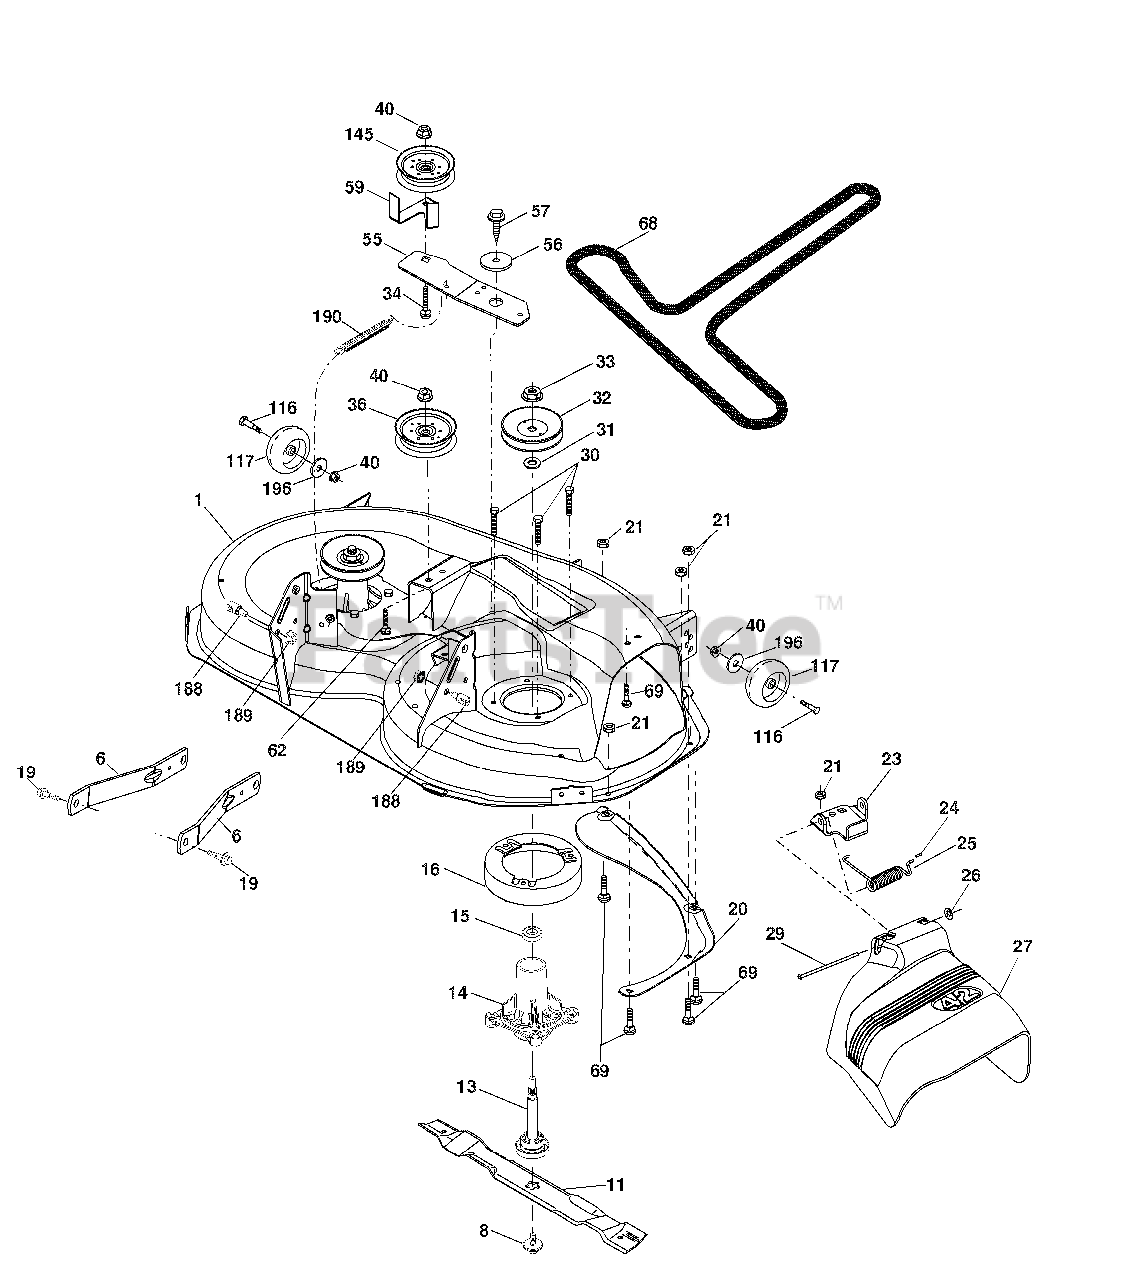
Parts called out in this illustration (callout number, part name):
1	Mower Housing
6	Arm Suspension
8	Bolt/Washer asm 7/16-20 unf
11	Blade, 42" Hi-Lift
13	Shaft Assembly, Mandrel
14	Housing, Mandrel
15	Bearing, Ball, Mandrel
16	Stripper, Mower Deck
19	Bolt, Shoulder
20	Baffle, Vortex
21	Nut, Crownlock 5/16-18 unc
23	Bracket, Deflector
24	Cap, Sleeve
25	Spring, Torsion, Deflector
27	Shield, Deflector
29	Rod, Hinge
30	Screw Thdrol Rolling Wsh Hd
31	Washer, Spacer
32	Pulley, Mandrel
33	Nut, Toplock, Flanged
34	Bolt Carr Sh. 3/8-16 x 1-1/2 Gr. 5
36	Pulley, Idler, Flat
40	Nut, Lock Flg. 3/8-16 unc
55	Arm, Idler
56	Spacer, Retainer
57	Screw 3/8-16 x 1
59	Guard, Tuv Idler
62	Bolt Rd Hd Sq Nk 3/8-16 unc x 2
69	Bolt
116	Bolt, Shoulder
117	Wheel, Gauge
145	Pulley Idler
188	Stud Fastener
189	Nut Lock Hex Flange
190	Spring Mower Drive
196	Washer 13/32 x 1-1/4 x 12 Ga.
